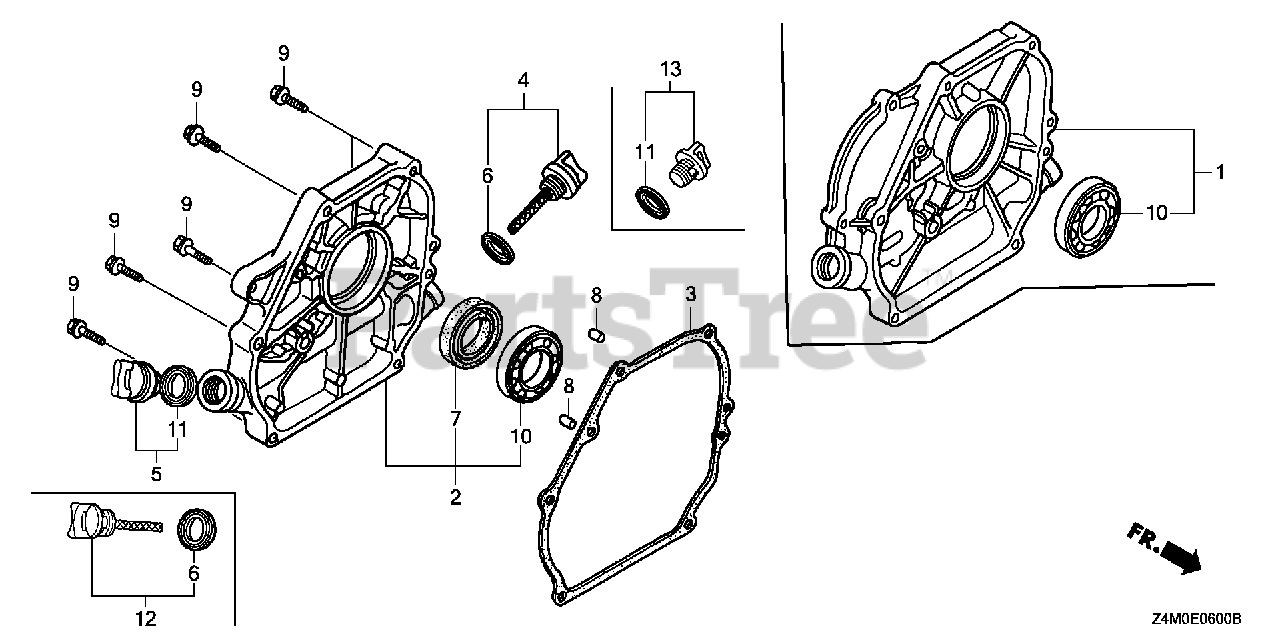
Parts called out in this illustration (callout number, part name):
1	COVER ASSY., CRANKCASE
3	GASKET, CASE COVER (NON-ASBESTOS)
4	CAP ASSY., OIL FILLER (GAUGE)(GRAY)
5	CAP ASSY., OIL FILLER (BLACK)
6	GASKET, OIL FILLER CAP
8	PIN, DOWEL (8X14)
9	BOLT, FLANGE (8X32)
10	BEARING, RADIAL BALL (6205)
11	GASKET, OIL FILLER CAP
